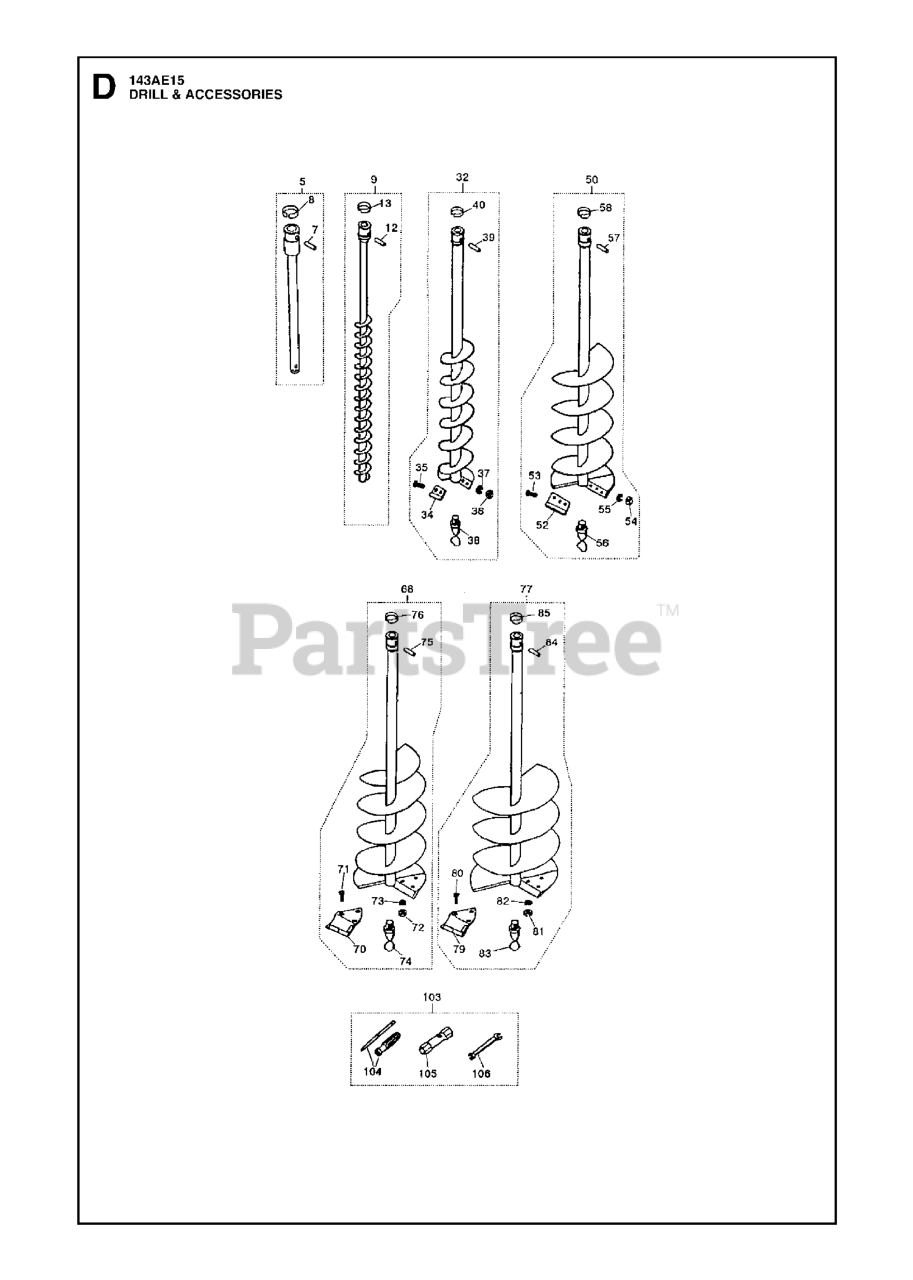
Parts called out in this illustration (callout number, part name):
5	EXTENSION JOINT 300MM
35	SCREW, M6 x 20
52	TIP.S150
53	SCREW, M6 x 20
71	SCREW, M6 x 20
80	SCREW, M6 x 20
106	WRENCH SPANNER
